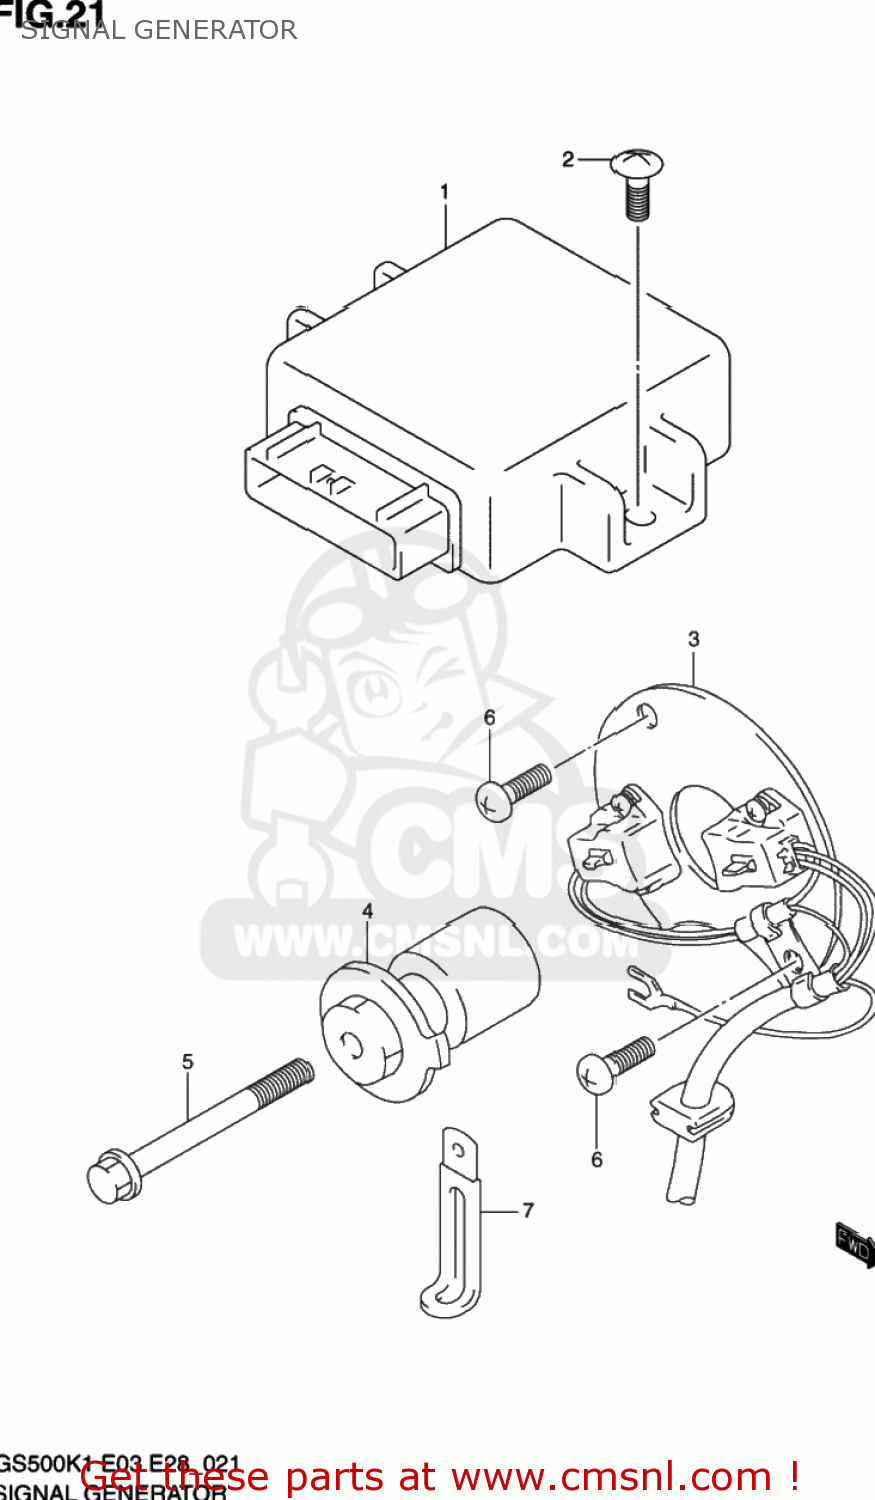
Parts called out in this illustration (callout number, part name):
1	IGNITER ASSEMBLY
2	SCREW
3	SIGNAL GENERATOR ASSY
4	ROTOR,SIGNAL
5	BOLT(6X60)
6	SCREW
7	CLAMP(L:65)
